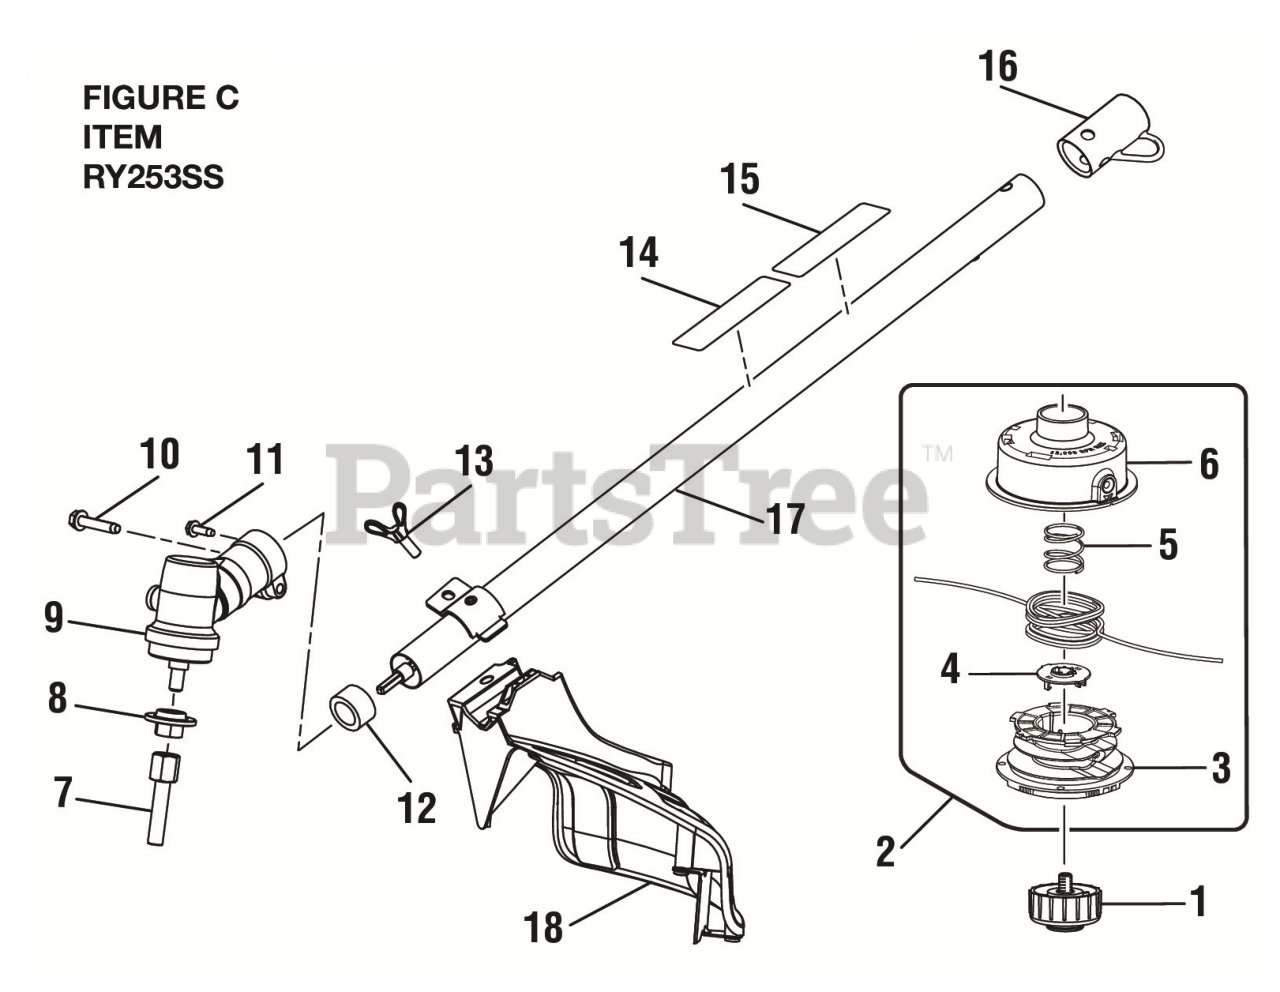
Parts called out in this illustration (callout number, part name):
1	RETAINING CAP, LEFT-HANDED THREAD
2	Reel Easy String Cutting Head Assembly
3	Spool Assembly
4	String Guide
5	Compression Spring
6	Housing and Eyelet Assembly
7	TRIMMER HEAD SHAFT ADAPTOR
8	FLANGED WASHER
9	Gear Case Assembly
10	Screw (1/4-20 x 1-1/4 in., Hex Washer Hd. S.T.)
11	Screw w/Washer (10-24 x 5/8 in., Hex Hd. T.F.)
13	Screw (#1/4-20 x 1-1/4 in. Hex Washer Hd.)
14	Ryobi EXPAND-IT Label
15	Warning Icon Label
16	Storage Hanger Cap
17	Straight Shaft Assembly
18	Grass Deflector Assembly (Incl. Key No. 11)
